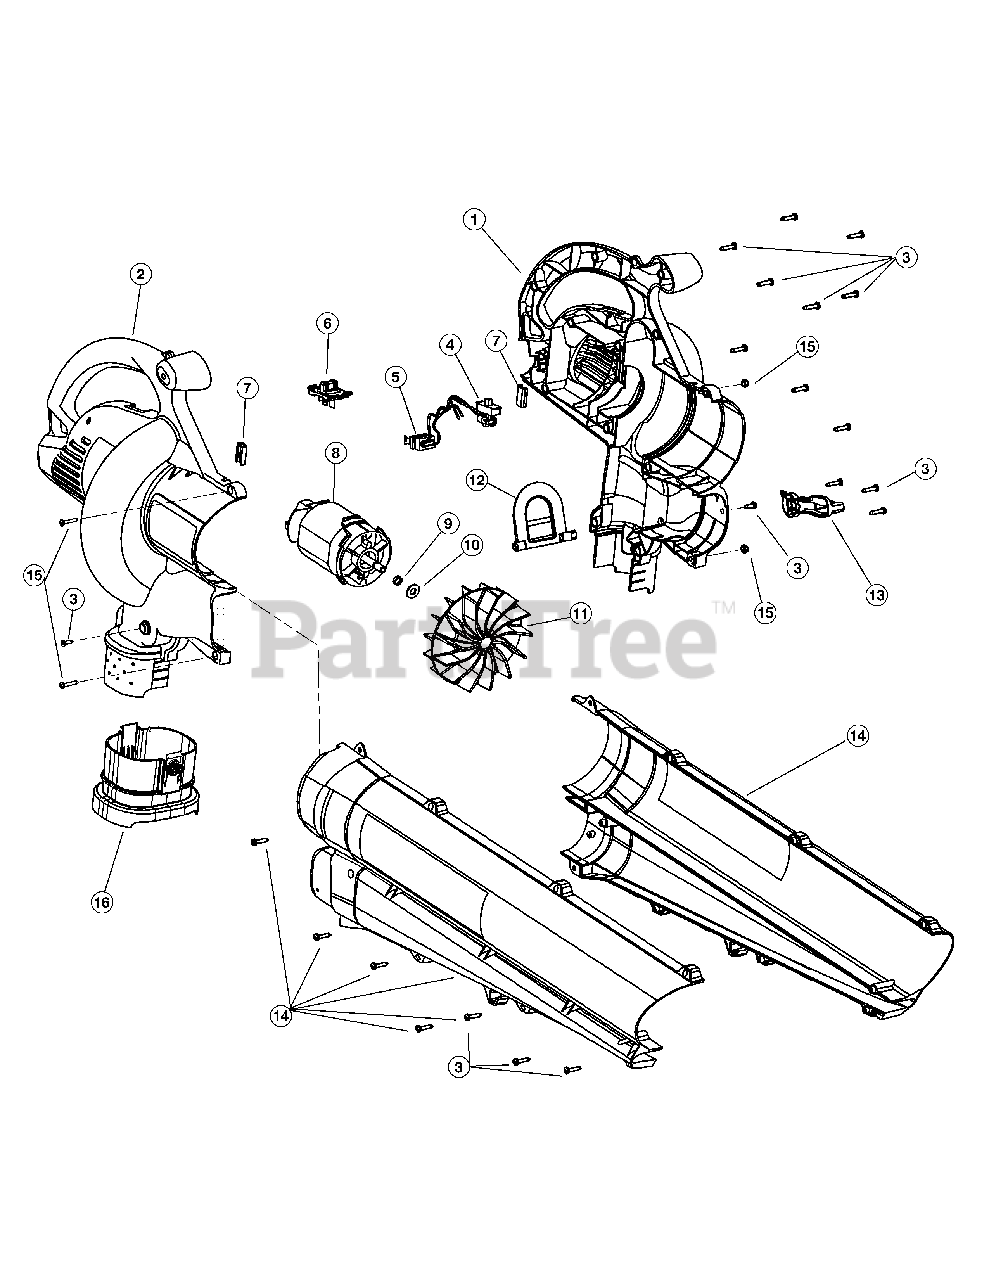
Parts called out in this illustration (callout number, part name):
1	Left Motor Housing
2	Right Motor Housing
3	Housing Screw
4	Switch Assembly
5	Power Connection Wire Assembly
6	Switch Lever
7	Rubber Cushion
8	Motor Assembly
12	Mode Control Flapper
13	Mode Control Lever
14	Blower/Vac Tube Assembly
15	Blower/Vac Tube Mounting Hardware
16	Vacuum Bag Adapter
